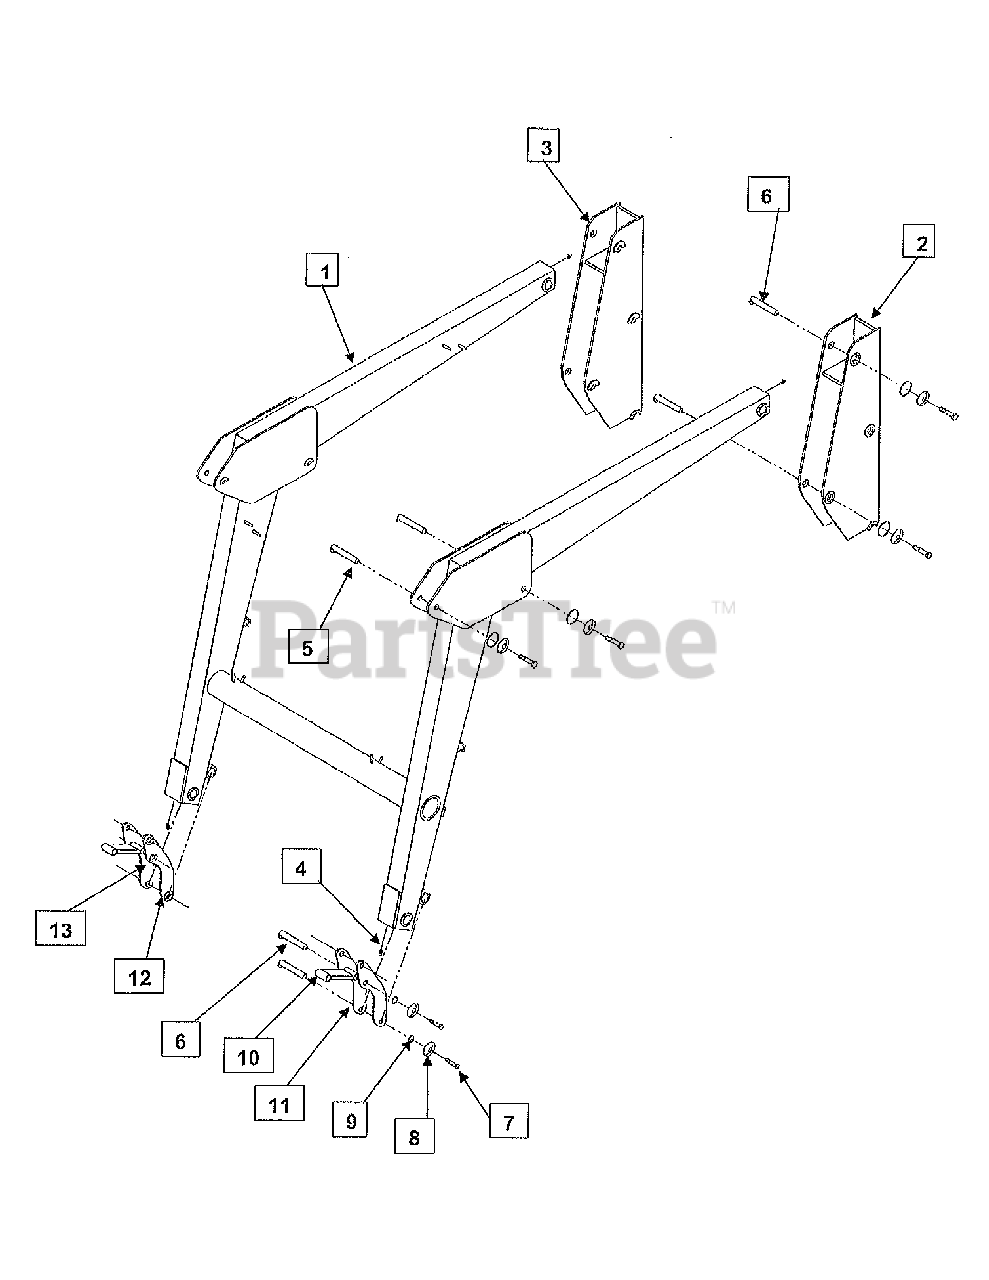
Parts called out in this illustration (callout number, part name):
1	Boom Assembly
2	Bearing Box, LH
3	Bearing Box, RH
4	Grease Fitting
5	Pivot Pin, 1" x 82mm
6	Pivot Pin, 1" x 99mm
7	Hex Head Cap Screw, 5/16" x 3/4"
10	Bucket Linkage Assembly
11	Boom Linkage Assembly, LH
12	Boom Linkage Assembly, RH
13	Boom Linkage
